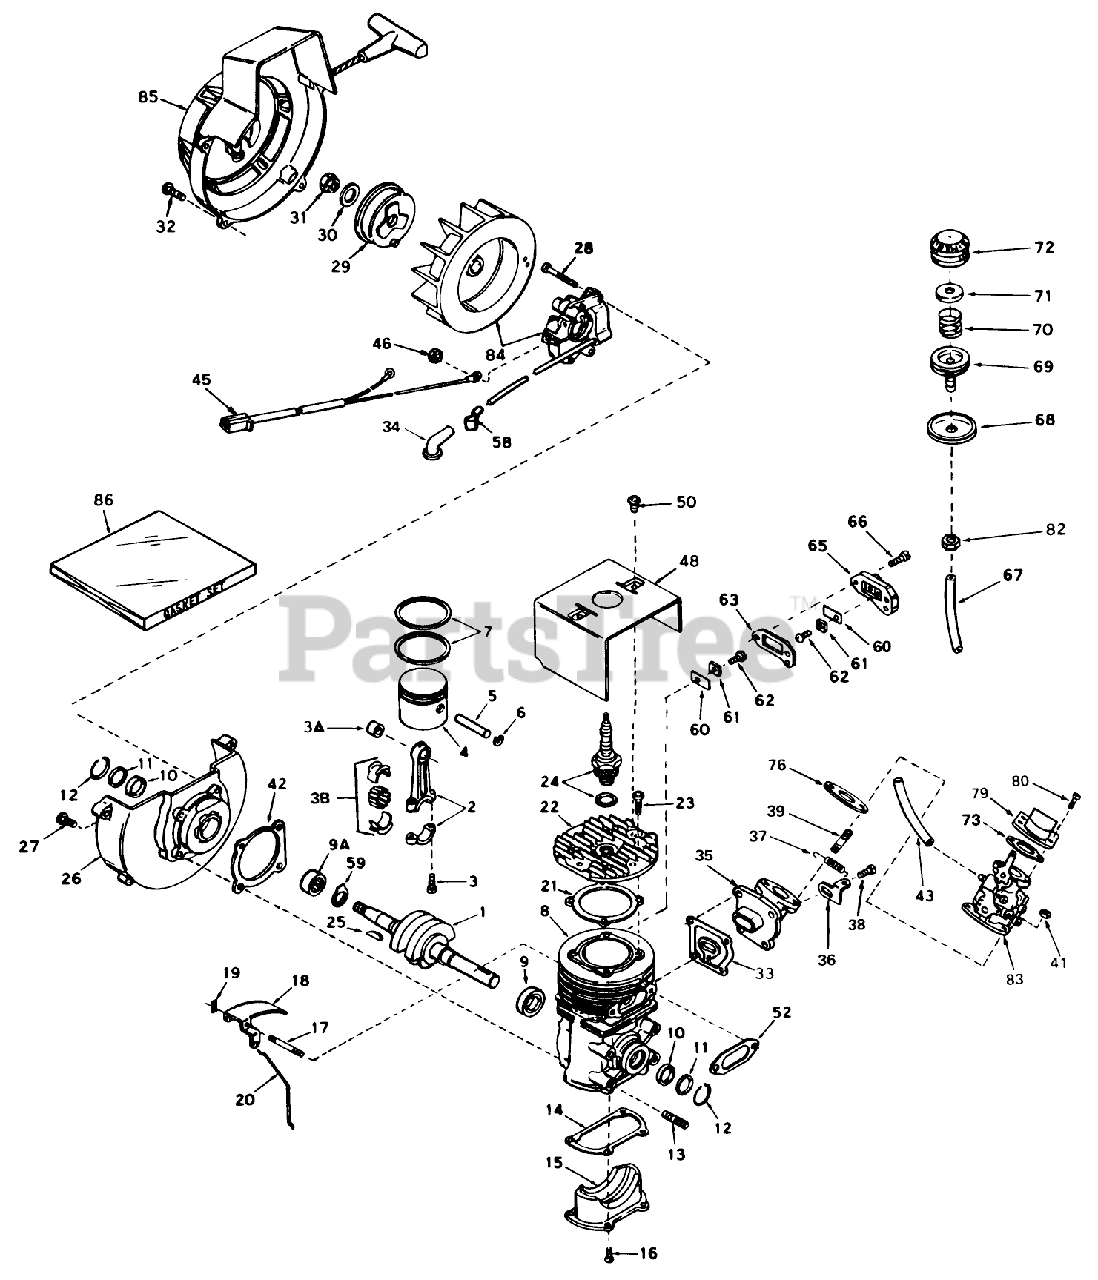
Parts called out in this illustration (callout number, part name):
1	Crankshaft
2	Rod Assembly, Connecting (Incl. #3, 3A 3B)
3	Bolt-Rod, Connecting
3A	Bearing-Cartridge
3B	Bearing Liner Set Needle
4	Piston
5	Pin, Piston
6	Ring-Retaning
7	Ring Set
8	Block Assy., Cylinder (Incl. Nos. 9, 10 thru 13 17)
9	Bearing Ball
9A	Bearing-Cartridge
10	Seal, Crankshaft
11	Retainer, Crankshaft Seal
12	Spring, Crankshaft Seal
14	Gasket, Cover
15	Plate, Cover
16	Screw (T-25, 10-24 x 1/2)
17	Shaft, Air Vane
18	Vane Assy, Air
19	Clip,Air Vane
20	Link, Governor
21	Gasket, Cylinder Head
23	Screw (T-30, 1/4-20 x 3/4)
24	Plug, Spark (J17LM or equiv.)
25	Key, Woodruff
26	Base Assy., Shroud (Incl. #9A-12)
27	Screw
28	Screw
29	Cup, Starter
30	Washer, Flat
31	Nut, Flywheel
32	Screw (T-30, 1/4-20 x 3/4)
33	Gasket, Port
34	51005 GIL.ROTARY TI
35	Elbow Assy., Adapter
36	Lever, Adjusting
37	Spring, Adjusting Lever
38	Screw
41	Hex nut
42	Gasket, Shroud Base
43	Line-Fuel
45	Harness, Wire
46	DECAL
48	Shroud, Cylinder
50	Screw (1/4-20 x 1/2)
52	Gasket-Muffler
58	Terminal, Lead wire
59	Washer, Thrust
60	Reed, Compression Release
61	Plate, Reed Hold Down
62	Screw
63	Gasket, Compression Release
65	Cover, Compression Release
66	Screw
67	Line, Primer
68	Retainer, Primer Bulb
69	Body, Primer
70	Spring, Primer Bulb
71	Washer, Primer Bulb
72	Bulb, Primer
73	Gasket
76	Gasket, Carburetor
79	Baffle-Carburetor
80	Screw
82	Hex nut
83	Carburetor (Incl. #76)
84	BRACKET S
85	Shroud Starter Assy.
86	GasketSet
